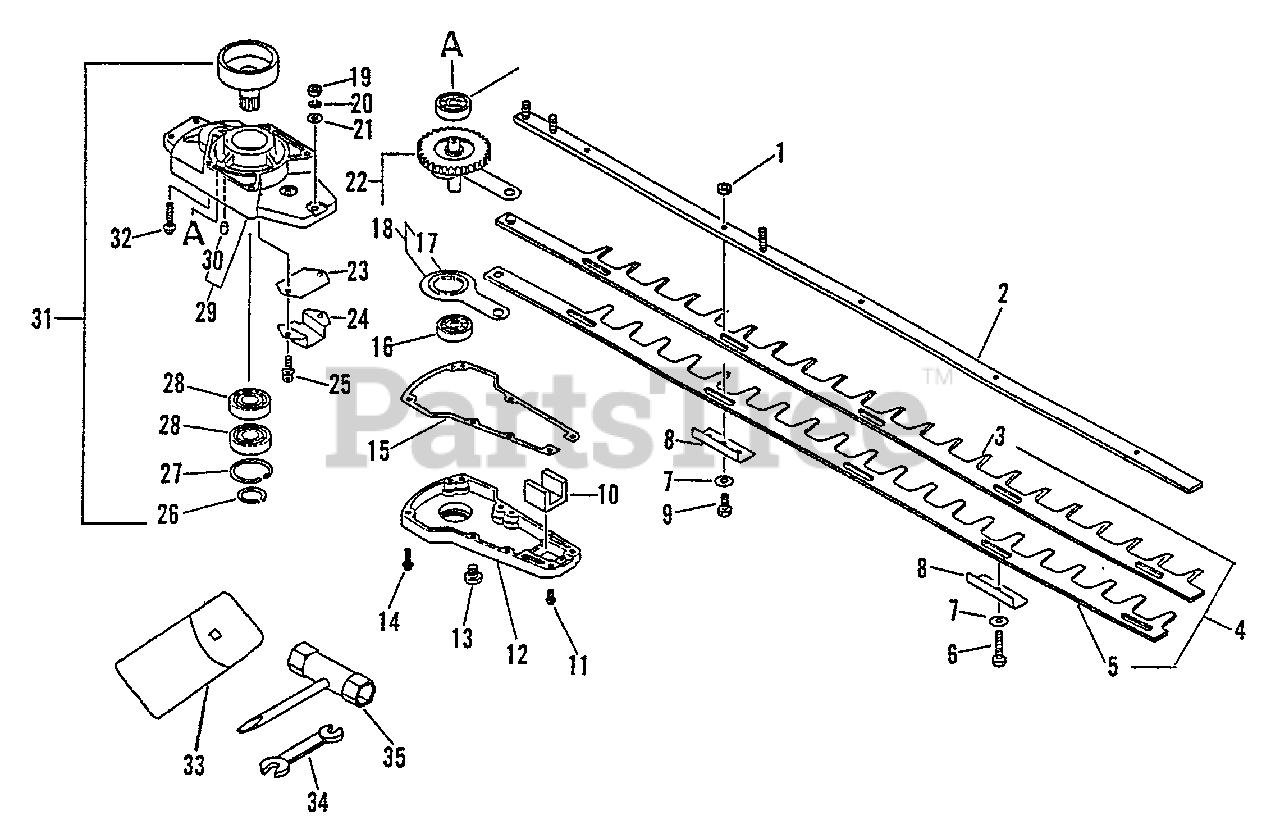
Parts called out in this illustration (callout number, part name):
1	NUT, LOCK 6
2	BAR, FRAME
3	BLADE - UPPER
4	TRIMMER BLADE SET
5	BLADE - LOWER
6	BOLT 6×40
8	INSULATOR
9	BOLT 6×22
11	SCREW 4×14
12	LID, GEAR CASE
13	BOLT 8×8 SP
14	SCREW 4×22
15	GASKET, GEAR CASE
16	BEARING, BALL 6200
17	BEARING, NEEDLE
18	CONNECTING ROD ASSY
19	NUT, HEX M6
20	WASHER, SPRING 6
21	WASHER 6.5×11.5×0.8
22	GEAR ASSY
23	GUIDE
24	GUIDE
25	BOLT 5×14
26	RING, RETAINING - 16
27	RING, SNAP 35
28	BEARING, BALL 6003
29	CASE, GEAR
30	PIN, LOCATING 4
31	DRUM, CLUTCH
32	SCREW 5×30
33	BAG, TOOL
34	SPANNER 8×10
35	WRENCH 14×19 W/S.DRIVER
